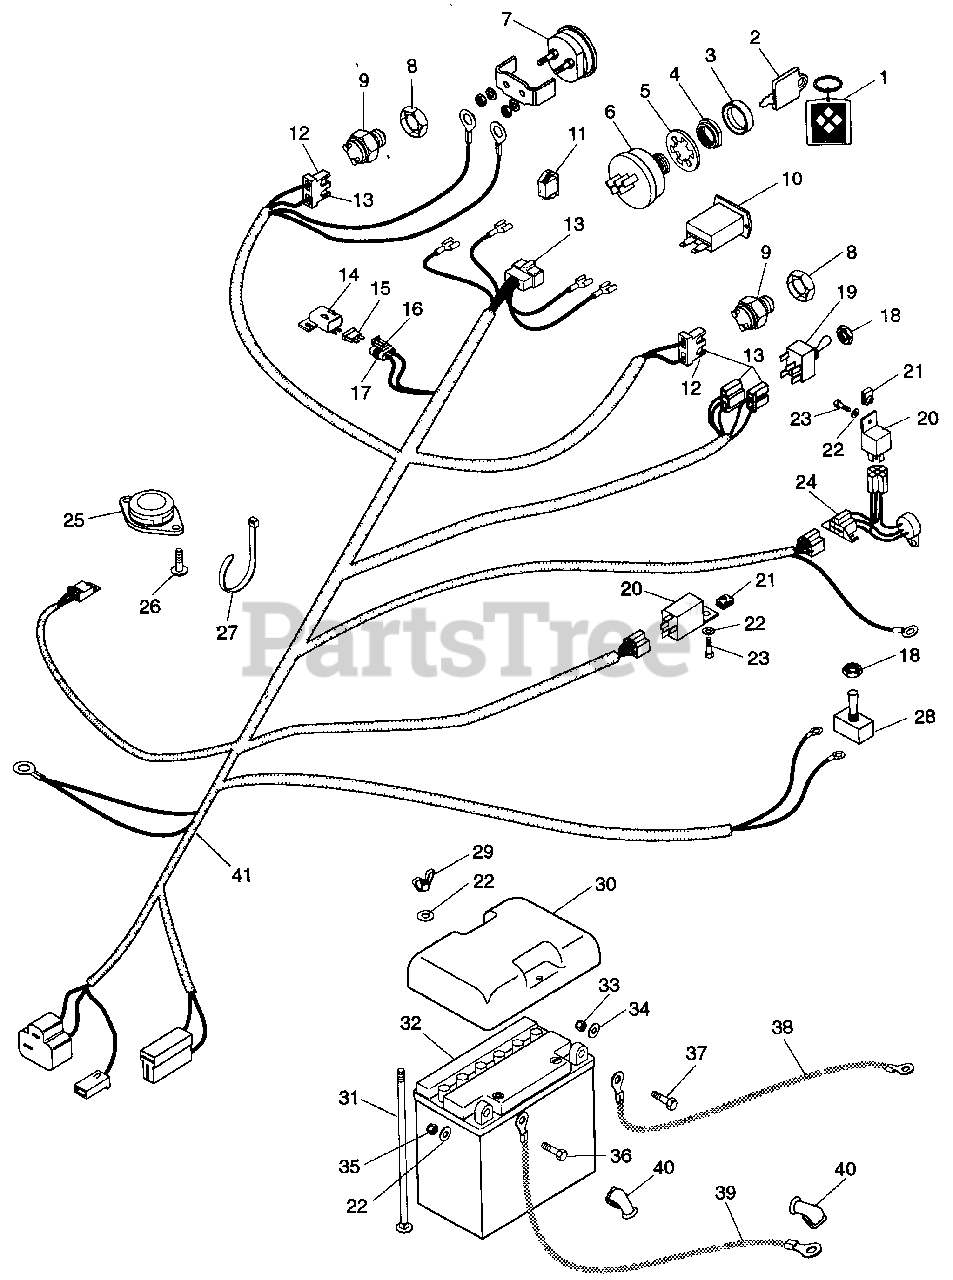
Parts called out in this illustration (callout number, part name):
1	KEY CHAIN
2	IGNITION SWITCH KEY
3	CAP-IGNITION SWITCH
4	NUT-PANEL .562-24 GRECO
5	WSHR-LOCK INT .563 X .040 PL
6	IGNITION SWITCH
7	GAUGE-AMMETER
8	NUT, STAMPED .56-18
9	SWITCH, NEUTRA START N.O.
10	HOUR METER
11	LIGHT, INDICATOR
12	CONN 2-WIRE SWITCH
13	TERMINAL
14	COVER
15	FUSE, 25 AMP
16	ASM, CONN WEATHER TIGHT
17	TERM, FOR 10-12 GA WIRE
18	NUT .50-27
19	SWITCH ASSEMBLY
20	RELAY
21	NUT-SPEED .25-20
22	WSHR-FL-STL .281 X .62 X .065 PL
23	BLT-HEX .25-20 X .63
24	MODULE, TIME DELAY
25	SEAT SWITCH
26	SCR-MCH .25-20 X .50
27	TIE WRAP, BLACK
28	SWITCH ASSEMBLY
29	NUT-WING .250-20
30	CVR, BATTERY
31	BLT-RDHDSQNK .25-20 X 7.00
32	12 VOLT BATTERY
33	NUT-LK-NYL .312-18 PL
34	WSHR-FL-STL .344 X .688 X .065 PL
35	NUT-LK-NYL .250-20 PL
36	BLT-HEX .25-20 X .75 PL GR 5
37	BLT-HEX .31-18 X 1.00 PL GR 5
38	CBL, NEGATIVE BATTERY
39	CABLE, BATTERY TO SOLENOID
40	BOOT INSULATOR
41	HARNESS, WIRING
